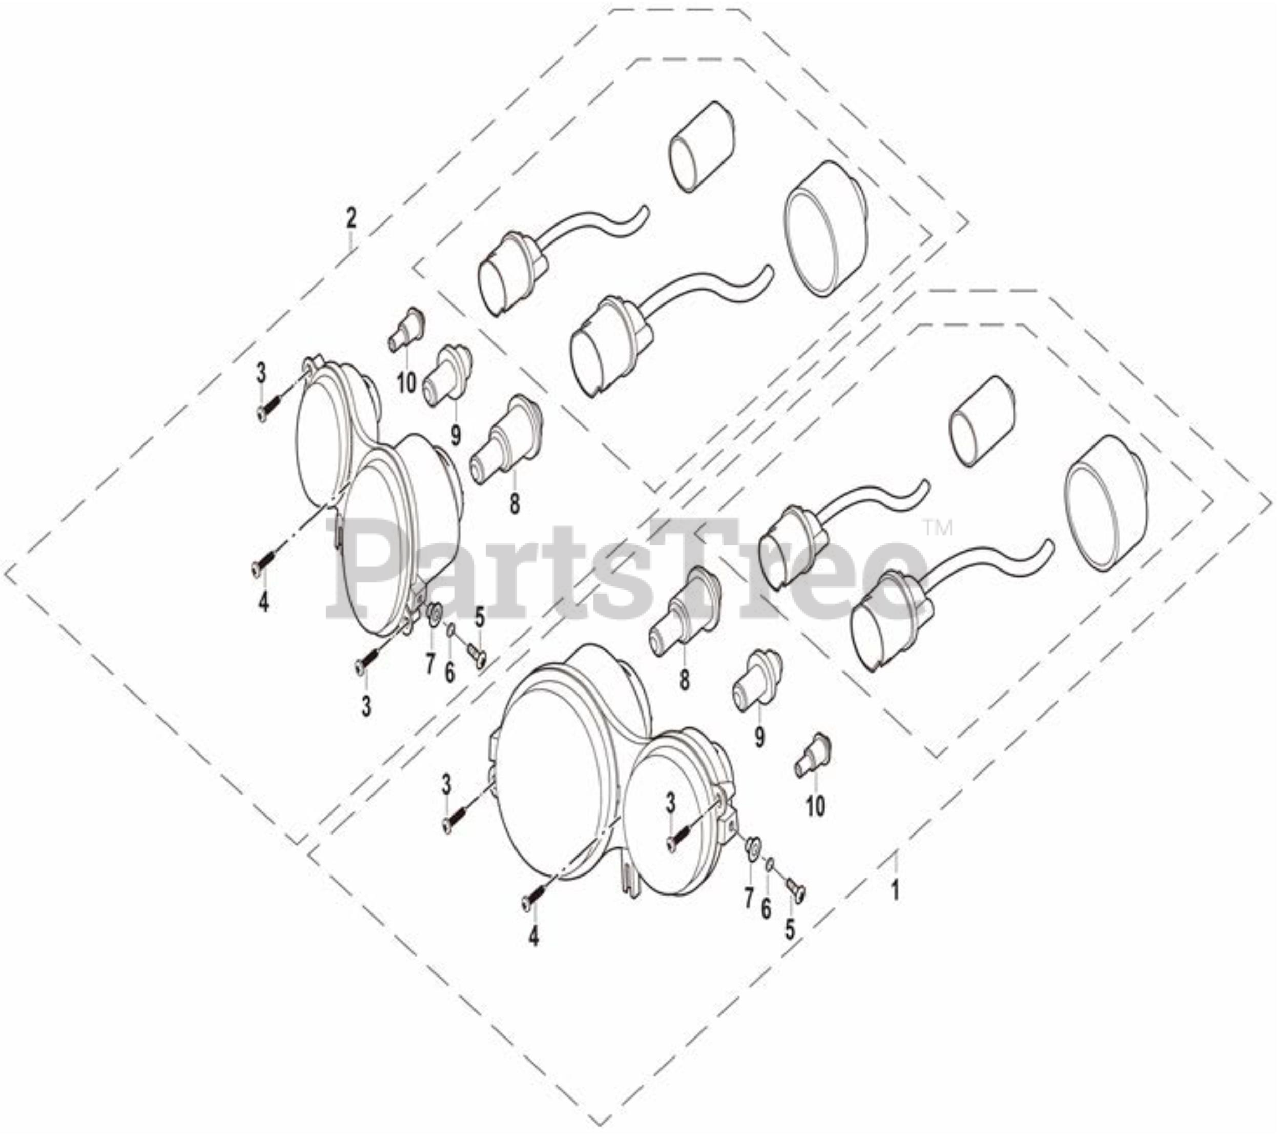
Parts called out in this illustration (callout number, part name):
1	Front Left Headlight Assy
2	Front Right Headlight Assy
3	Cross recess pan head screw M4X12
4	Cross recess pan head screw ST3.6X10
5	Cross recess pan head screw M4X16
6	Flat washer 4
7	Flanger bush 5.1X8X5
8	Head lights bulb S2?12V?35W/35W
9	Position light bulb 12V?W5W
10	Turning lights bulb 12V?R10W
